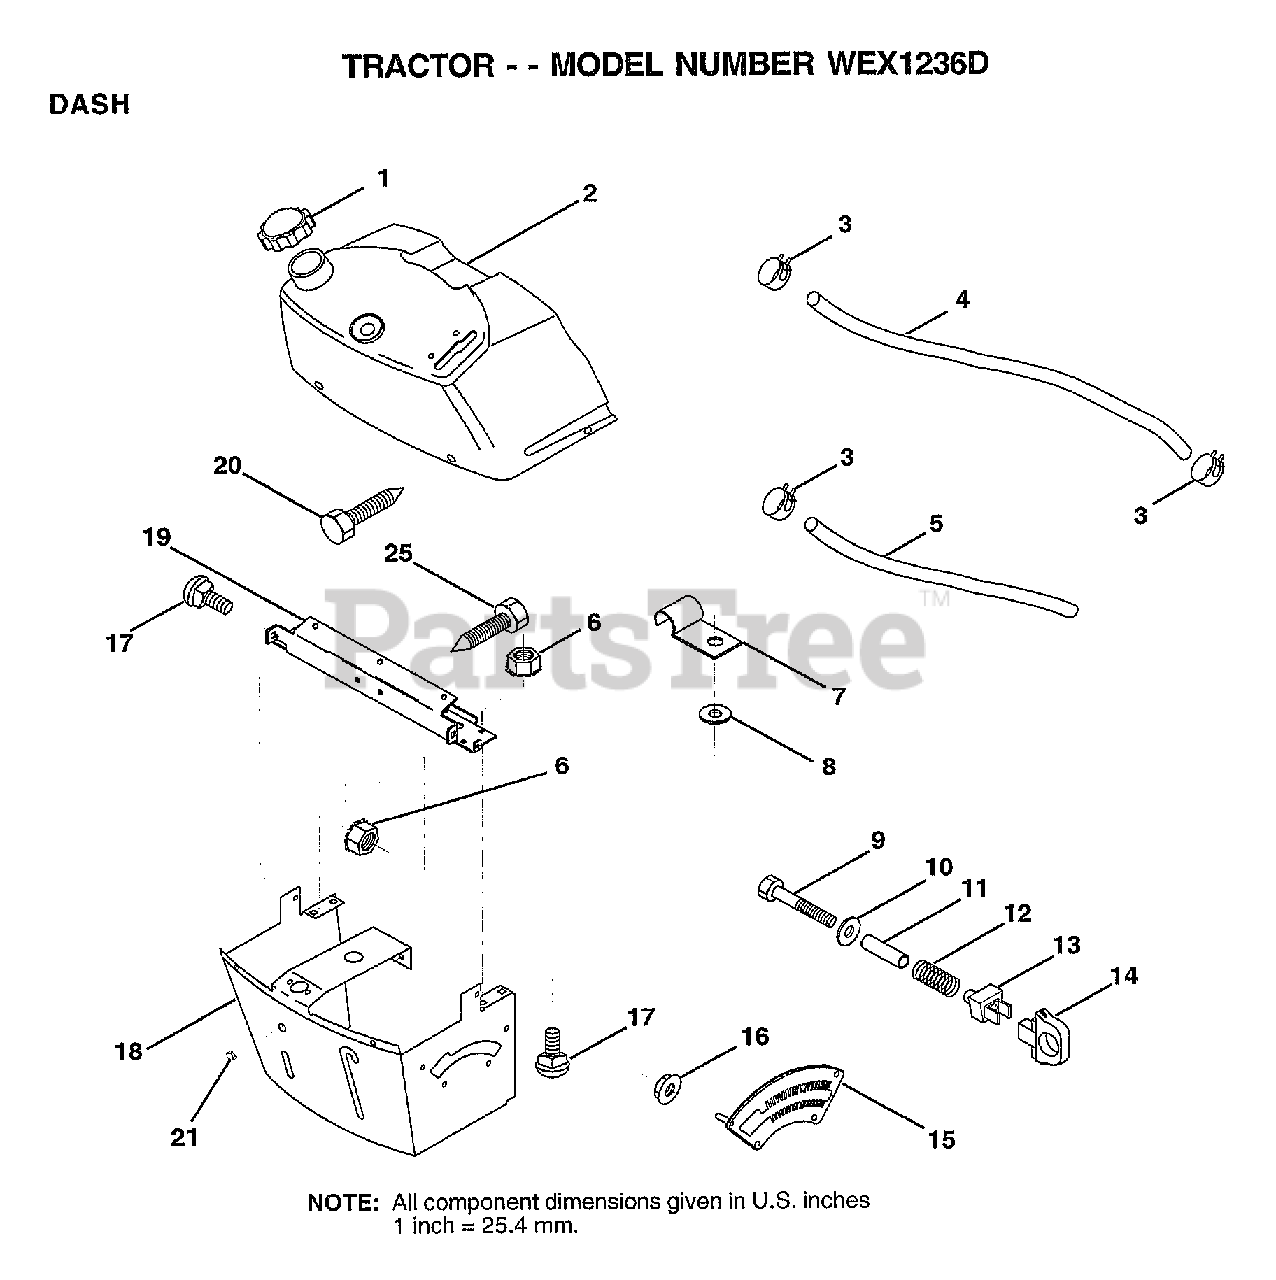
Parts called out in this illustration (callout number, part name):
1	CAP BLK FUEL LR
2	TANK.ASM.DASH.LR
3	HOSE CLAMP
5	FUEL LINE T
6	NUT HXKEP 1/4X20
7	CLIP T
8	WASHER PM
9	BOLT
11	SPACER SPLIT
12	SPRING M
13	"KNOB,HGT RETAINER"
14	KNOB
15	ADJUSTER QUAD
16	NUT
17	BOLT
18	SUPT ASSY DASH
19	CROSS BRACE
20	SCREW.1/4-20X1/2
21	PLUG DOME
25	SCREW LT
